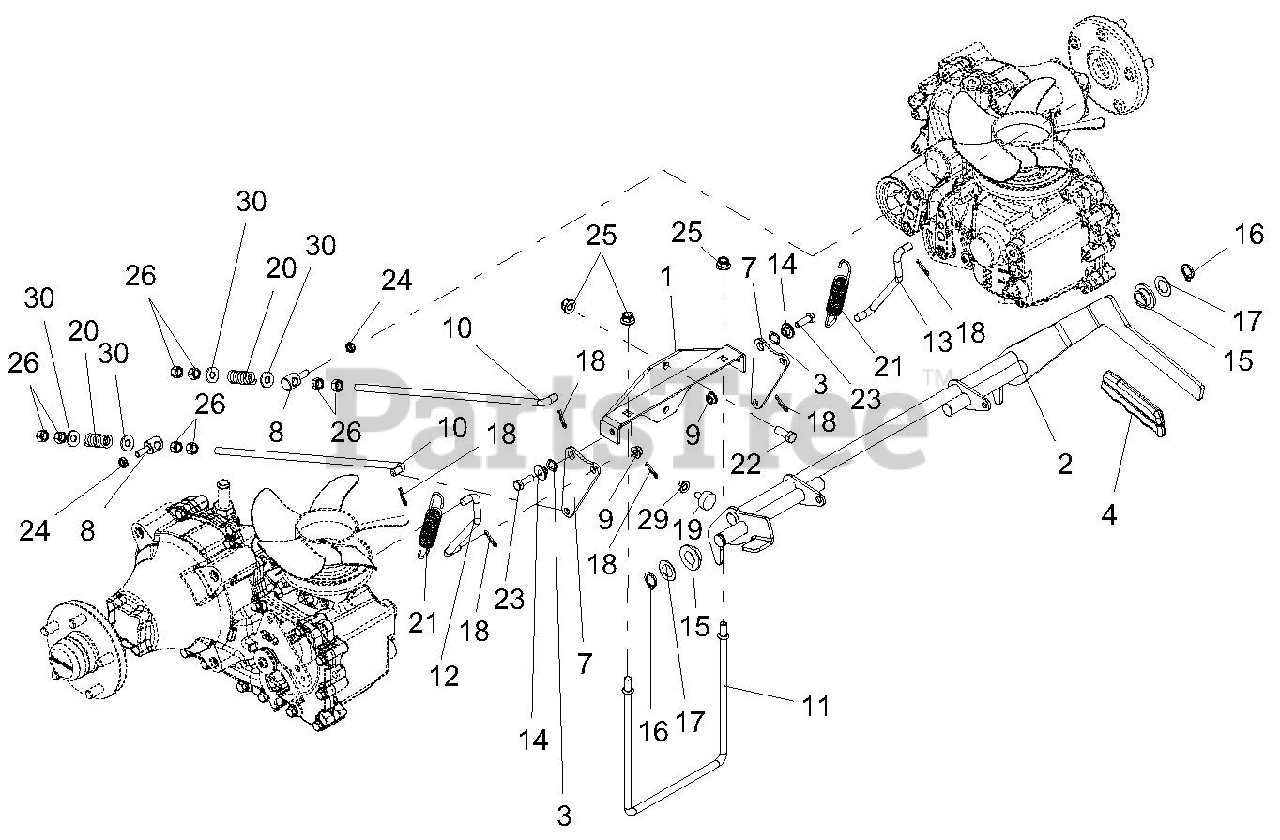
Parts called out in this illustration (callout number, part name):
1	WMT, SPRING ANCHOR BRKT
2	WLDMT, PARKING BRAKE LEVER
3	WAVE WASHER .531X.781X.125 FH
4	GRIP, PARKING BRAKE
7	PLATE, BRAKE PIVOT
8	TRUNNION, .31-18
9	NUT, LK-TOP-FLG .312-18 YWZC
10	ROD, BRAKE ADJ.
11	ROD, BRAKE MTG
12	LINKAGE, RH BRAKE ACTUATING
13	LINKAGE, LH BRAKE ACTUATING
14	BSHG.-FLG. .312 X .500 X .344
15	BUSHING, FLANGE
16	RG-RING-EXT .689 X .078
17	WHST-HDND-THRST
18	PIN, HAIR
19	BUMPER, RUBBER
20	SPRING, COMPRESSION
21	EXT. SPRING
22	BLT-HEX .38-16X1.00 GR5 YWZC
23	BLT-HEX .31-18X1.00 GR5 YWZC
24	NUT-LK-CTR-JAM .31-18 YWZC
25	NUT-LK-NYL-FLG .38-16 YWZC
26	NUT-HEX .38-16 YWZC
29	NUT-SPNLK-FLG .312-18 YWZC
30	WSHR-FL-STL.38X.875X.083 YWZC
